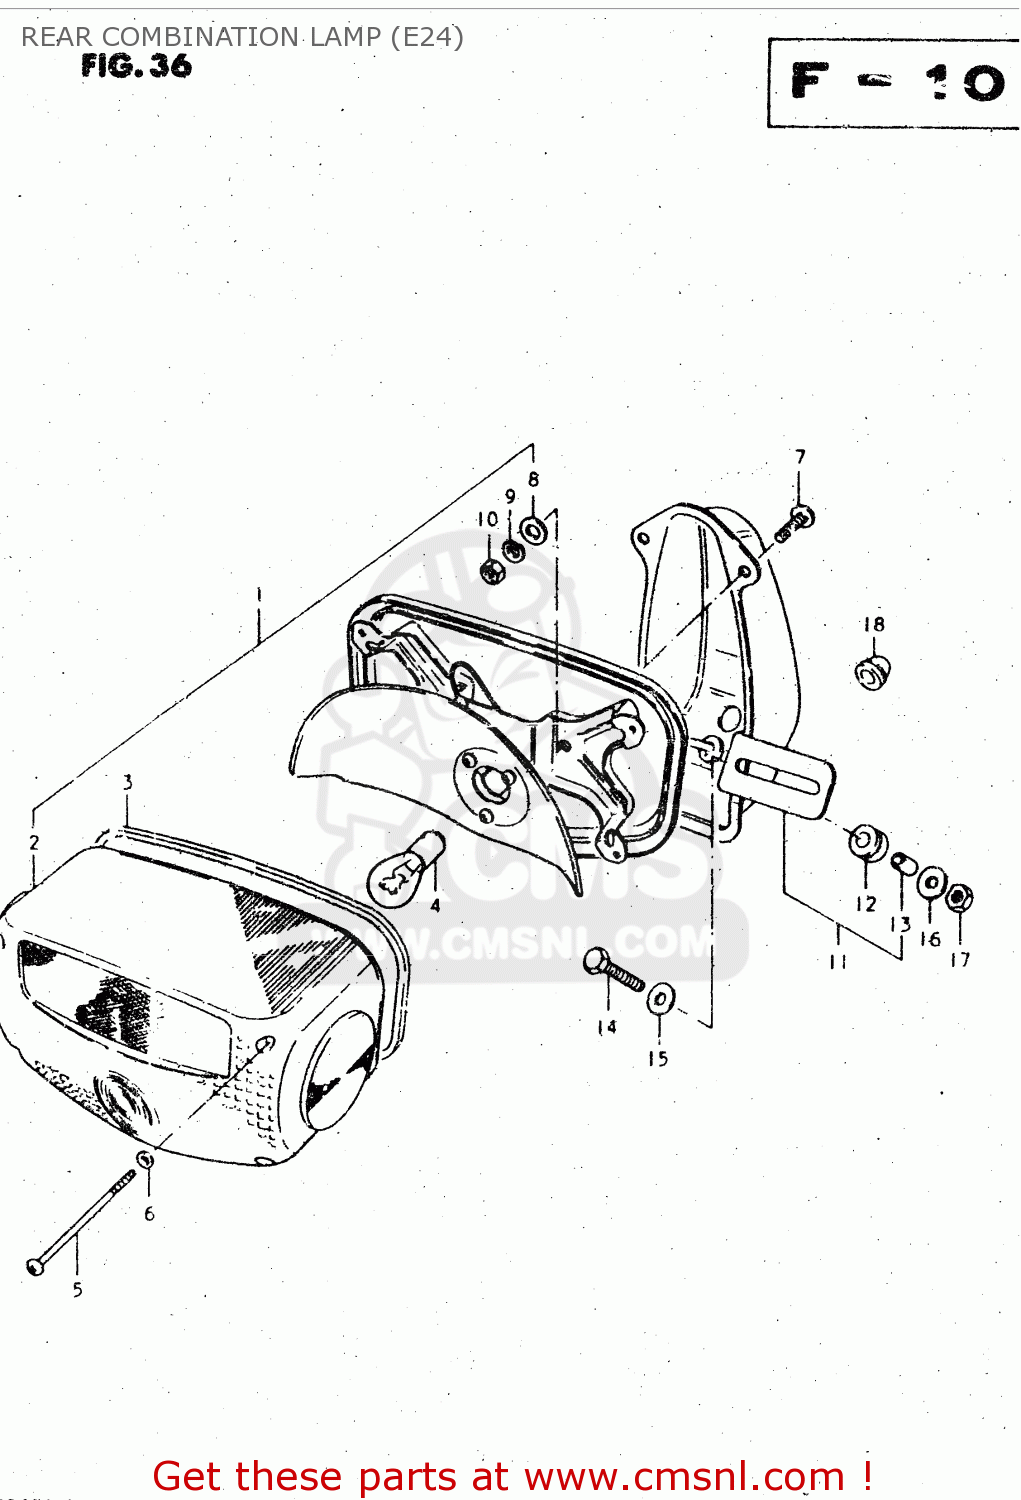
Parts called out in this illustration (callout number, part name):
1	LAMP UNIT,REAR COMBINATION
2	LENS,REAR COMBINATION LAMP
3	GASKET (NAS)
4	BULB(12V23W)
5	SCREW (4X55)
6	GASKET (NAS)
7	SCREW 6X12
8	WASHER
9	LOCK WASHER
10	NUT
11	BRACKET UNIT,TAIL LAMP
12	CUSHION
13	SPACER
14	BOLT
15	WASHER (6.5X20X1.2)
16	WASHER
17	NUT
18	GROMMET
